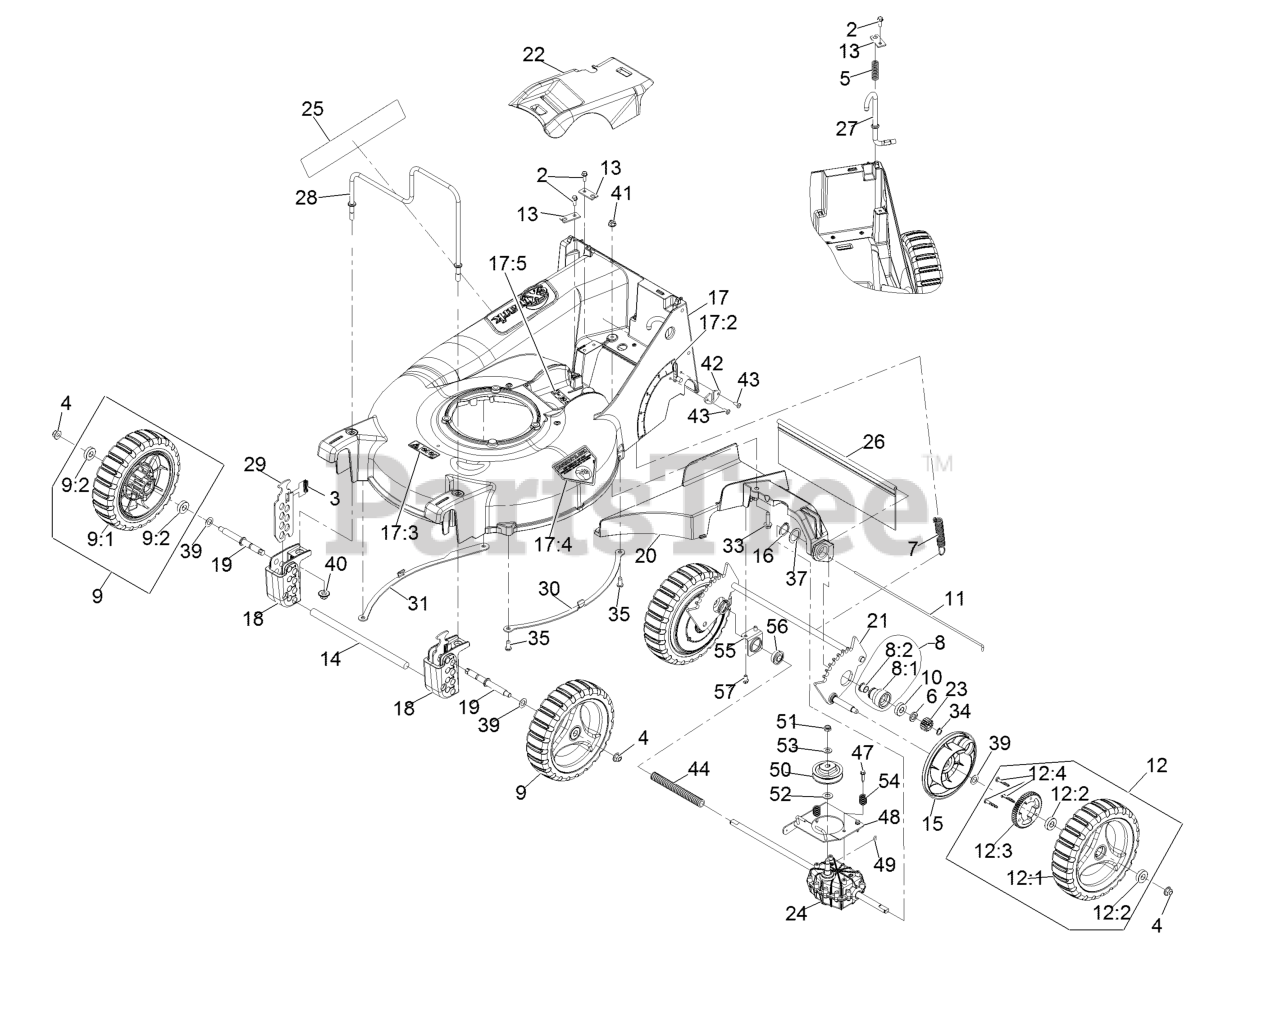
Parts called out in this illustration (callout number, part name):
2	Screw-HWH 1/4-20 X .62
3	Spring-Compression
4	Nut-Nyloc 3/8-16 Flg
5	Spring-Compression
6	Spacer-Bushing
7	Spring-Extension
8	Housing ASM
8:1	Housing-Bearing
8:2	Bearing-Flange
9	Wheel ASM, 9" W/Bearings
9:1	Wheel ASM, 9"
9:2	Bearing-Ball
10	Bearing-Ball
11	Rod,Shield
12	Wheel ASM, 9 W/Gear
12:1	Wheel ASM, 9"
12:2	Bearing-Ball
12:3	Gear-Wheel, 52T
12:4	Stud-Drive
13	Bracket,Mount
14	Rod,Bumper
15	Cover,Gear
16	Ring-Retaining
17	Deck W/Decals
17:2	Decal-Height Of Cut
17:3	Decal-Warning, Blade
17:4	Decal-Danger
17:5	Decal-Danger
18	Block,Front Quadrant
19	Axle-Wheel
20	Bracket-Transmission And Chute
21	Wld,Rear Axle P21
22	Cover,Belt
23	Gear-Pinion, 15T
24	Transmission-HD, 4.5/1
25	Decal-Comm 21 X-Series
26	Shield-Trailing P21
27	Rod-Height Adj P21
28	Guard,Engine
29	Plate, Front Height
33	Screw-HWH 5/16-18 1 1/4 Tf
34	Ring-Retaining
35	Screw-Button Head 5/16-18 X .725 Tf
40	Nut-Nyloc 3/8-16 Flg
41	Nut-Nyloc 5/16-18 Flg
42	Plate,Wear
44	Cover-Shaft-Drive
47	Screw-Special
48	Transmission Plate ASM
49	Key-Woodruff 1/8 X 1/2
51	Nut-Nyloc 3/8-24 Thin
52	Washer-Thrust
53	Washer-Flat
54	Spring,Compression
55	Mount-Bearing
56	Bearing-Ball
57	Screw-HWH 1/4-20 X .50
